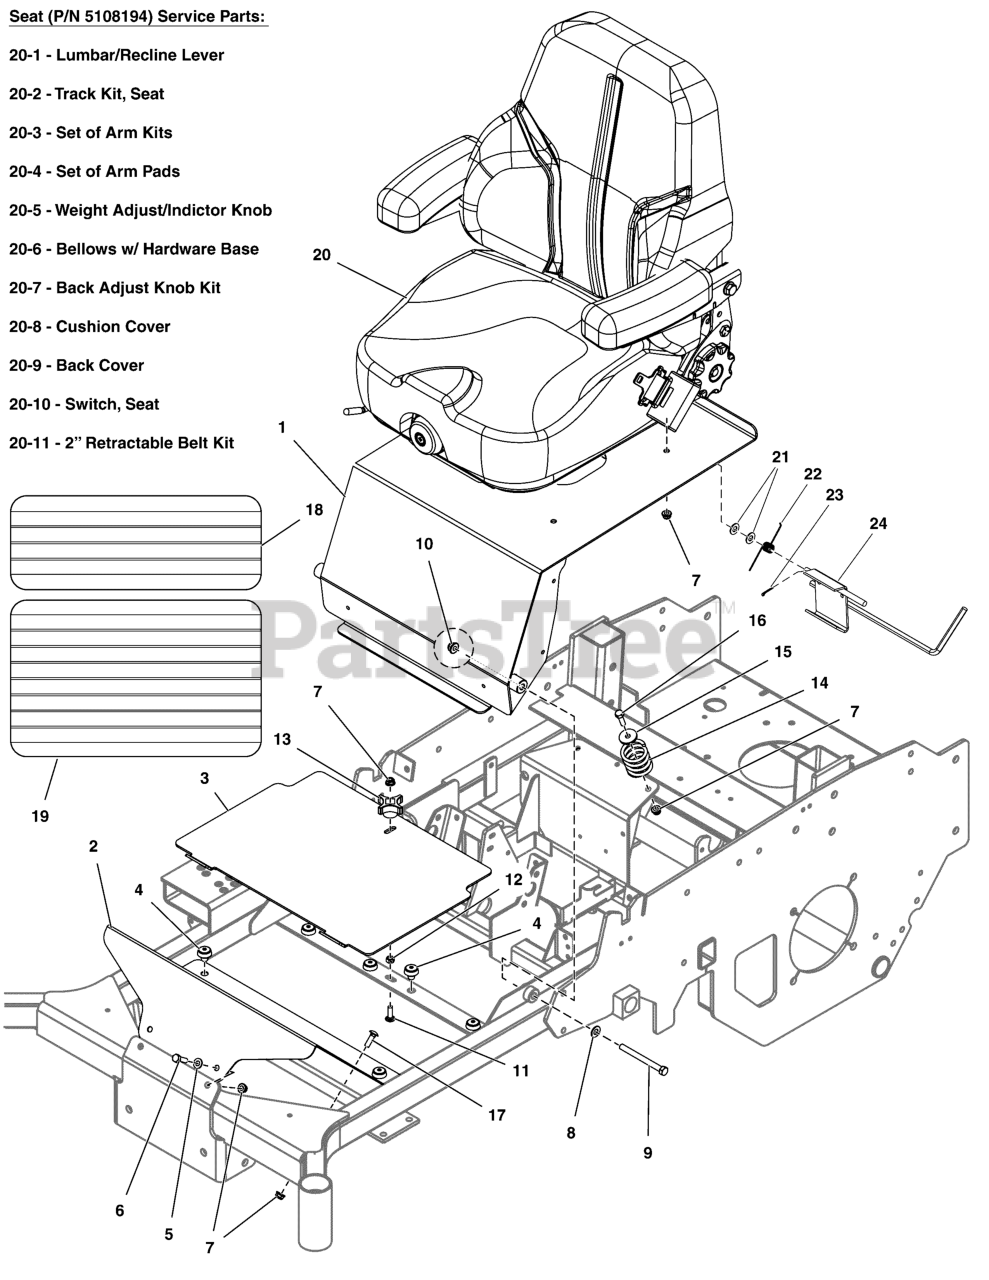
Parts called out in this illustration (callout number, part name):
1	ASSM, SEAT PLATE W/ DECAL, F160Z-DOM
2	PLATE, FLOOR, NON REMOVABLE - RED
3	PLATE, FLOOR, REMOVABLE, IS700 - RED
4	MNT, VBRTN, RBBR
5	WASHER, 5/16" SAE
6	BOLT, 5/16-18 X 1" GRD5 YZ
7	NUT, 5/16-18 HEX NYLOCK FLANGE NUT
8	WASHER, 3/8 SAE
9	BOLT, 3/8-16 X 4" GD5 CZ
10	NUT, 3/8 - 16 HEX NYLOCK FLANGE
11	BOLT, 5/16-18 X 1-1/4, CARRIAGE, GD5, CZ
12	NUT, 5/16-1/8, HEX, CNTR LK, ZINC PHOS/OIL
13	KNOB-INT THR .312-18 4-ARM 2.12WD 1.06LG
14	SPRING, SEAT SUPPORT
15	WASHER, .34 X 1.25 X 10 GA
16	BOLT, 5/16-18 X 1-1/2" GD5 YZ
17	BOLT, 5/16-18 X 3/4, CARRIAGE, GD5, CZ
18	SAFETY WALK, FLOOR REST, 16.00 X 6.00
19	SAFETY WALK, FLOOR PLATE, S50X, 10X17.13
20	SEAT, HIGH BACK,SUSP,SWITCH & SEAT BELTS
20-1	LUMBAR/RECLINE/ISO LVR W/ RLL PIN BS
20-2	4" SINGLE LOCKING TRACKS BASE
20-3	SET OF ARM KITS
20-4	SET OF ARM PADS
20-5	WEIGHT ADJUST INDICATOR KNOB ASSY BASE
20-6	BELLOWS W/ HARDWARE BASE
20-7	BACK ADJUSTMENT KNOB KIT
20-8	CUSHION COVER
20-9	SEAT BACK COVER
20-10	SWITCH, SEAT
20-11	2" RETRACTABLE BELT KIT
21	WASHER, 3/8 SAE
22	PIN, 3/32 X 0.750, COT, ZINC/CLEAR
23	SPRING, TORSION, LH, .0625OD
24	WELD, SEAT LATCH HOOK, W/ SPRING - BLK
